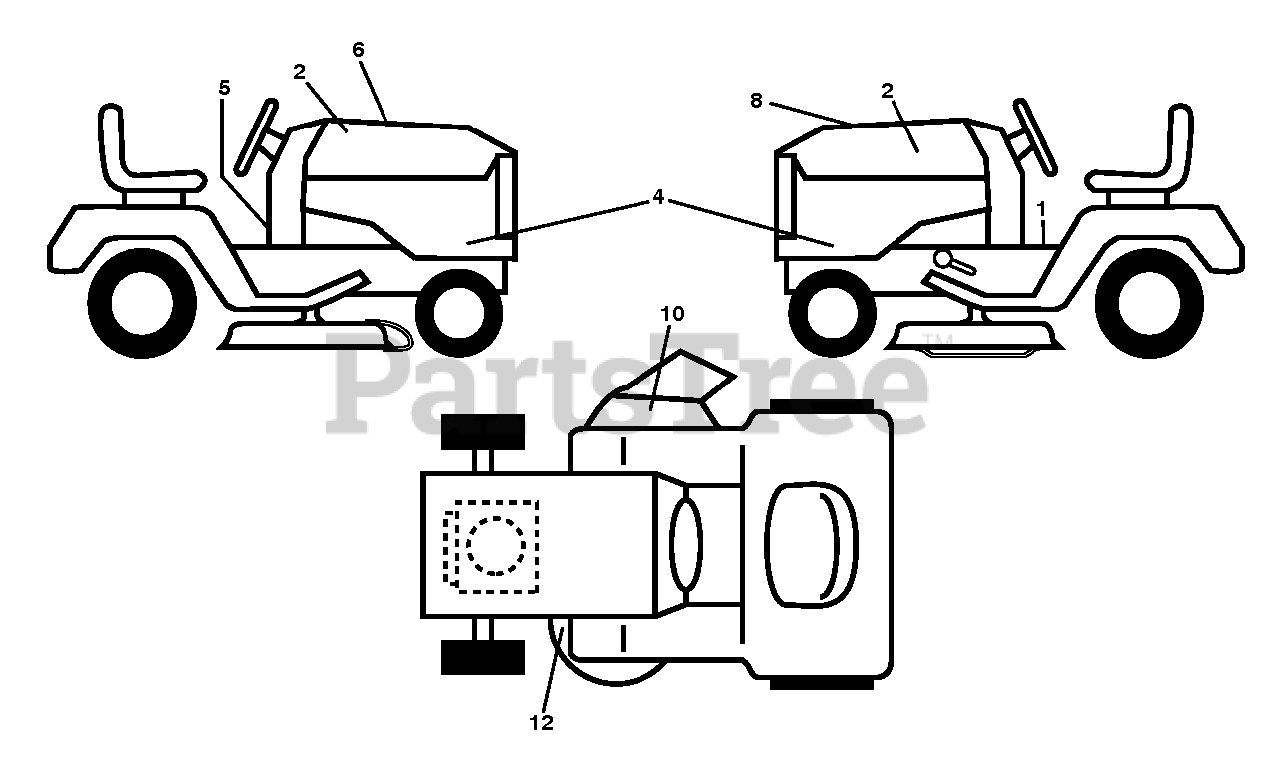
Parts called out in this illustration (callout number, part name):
1	DECAL.FENDER.WARNING.ENGLISH
2	Decal, WB 178MM 15 Husqvarna NEWBRAN
4	Decal, Side Panel GT2 Set YTH20K42
5	Warning Decal, Spark Arrest
6	Decal, Replacement Kohler KT7 TLW 42C K46L
8	DECAL.WARNING.CUST.RESP.E85.
10	DECAL, DECK DEFLECTOR, WARNING
12	DECAL.V-BELT.SCH.42/46"MEC/ELE
